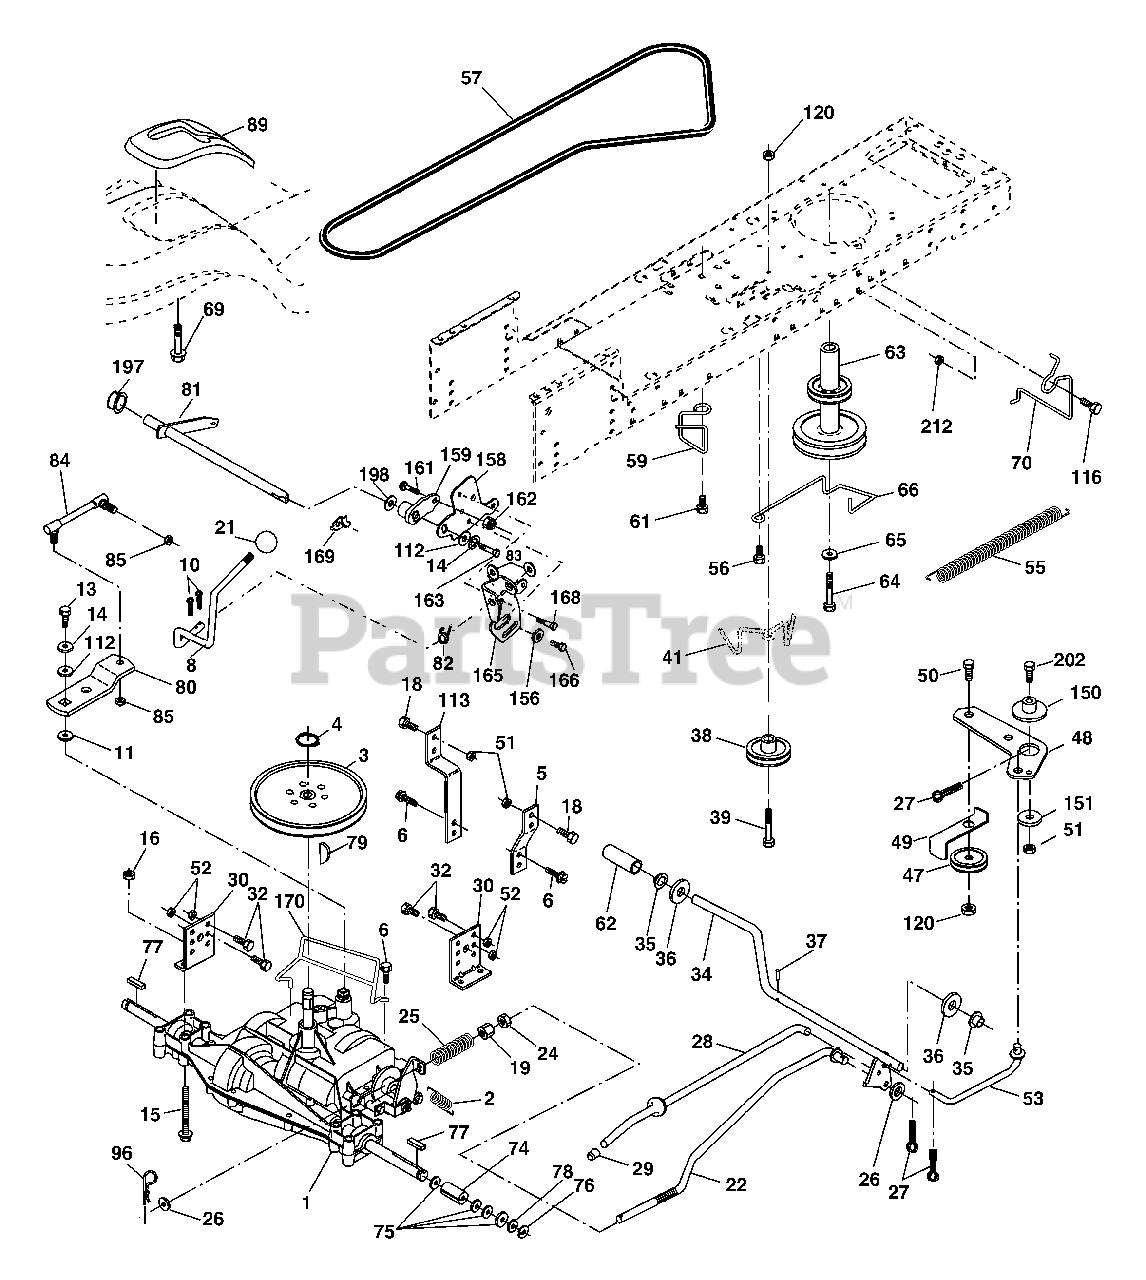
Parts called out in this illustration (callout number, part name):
2	Spring Return Brake T/a Zinc
3	Pulley Transaxle 18" tires
4	Ring Retainer # 5100-62
5	Strap Torque 30 Degrees
6	Screw 5/16-18 x 3/4
8	Rod Shift Fender Adjust Lt
10	Pin Cotter 1/8 x 1 Cad
11	Washer Plate Shf 388 Sq Hole
13	Bolt 1/4-28 unf Gr. 8 W/Patch
14	Washer Lock Hvy Helical
15	Bolt Hex FLGHD 5/16-18 Gr. 5
16	Nut Lock Hex w/ins 5/16-18
18	Bolt, Fin Hex 3/8-16 unc x 1 Gr. 5
19	Nut Lock 3/8-16 unc
21	Knob
22	Rod Brake Blk Zinc 26 840
24	Nut Hex Jam 3/8-16 unc
25	Spring Rod Brake 2 00 Zinc
26	Washer 13/32 x 13/16 x 16 Ga.
27	Pin Cotter 1/8 x 3/4 Cad
28	Rod Brake Parking LT/YT
29	Cap Brake Parking
30	Bracket Mtg Transaxle
32	Bolt Hex Hd 5/16-18 unc x 3/4
34	Shaft Asm Pedal Foot
35	Bearing Nylon Blk 629 Id
36	Washer 21/32 x 1 x 16 Ga
37	Pin Roll 3/16 x 1"
38	Pulley Composite Flat
39	Bolt Fin Hex 3/8-16 unc x 2-3/4
41	Keeper Belt Flat Idler
47	Pulley Idler V Groove Plastic
48	Bellcrank Asm
49	Retainer Belt Style Spring
50	Bolt Carr. Sh. 3/8-16 x 1-1/2 Gr. 5
51	Nut Crownlock 3/8-16 unc
52	Nut Crownlock 5/16-18 unc
53	Link Clutch
55	Spring Return Clutch 6 75
56	Screw 3/8-16 x 1-1/4
57	V-Belt Ground Drive 95 25
59	Keeper Belt Span Ctr
61	Screw 3/8-16 x .875
62	Cover Pedal Blk Round
63	Engine Pulley
64	Bolt Hex 7/16-20 x 4 x Gr. 5-1.5 Thr
65	Washer Lock Hvy Hlcl Spr 7/16
66	Keeper Belt Engine Foolproof
69	Screw Hex wsh Hi Lo 1/4 x 1/2 unc
70	Guide Belt Mower Drive RH
74	Spacer Axle
75	Washer 25/32 x 1 1/4 x 16 Ga.
76	E-ring #5133-75
77	Key Square 2 0 x 1845/ 1865
78	Washer 25/32 x 1-5/8 x 16 Ga.
79	Key Woodruff #9 3/16 x 3/4
80	Arm Shift
81	Shaft Asm Cross Tap. PMST/20
82	Spring Torsion T/a
83	Washer 17/32 x 3/4 x 16 Ga.
84	Link Transaxle PMST/18" Zinc
85	Nut Lock Center 1/4 - 28 FNTHD
89	Console Shift STLT
96	Retainer Spring 1"
112	Washer 9/32 x 3/4 x 10 Ga.
113	Strap Torque LT
116	Bolt Rdhd Sq Neck 3/8-16 x 1
120	Nut Lock Flg. 3/8-16 unc
150	Spacer Retainer
151	Washer 13/32 x 2 x 10
156	Washer Srrted 5/16 ID x 1.125
158	Bracket Shift Mount
159	Hub Tapered Flange Shift Lt
161	Bolt Rdhd Sqnk 1/4-20 x 3/4 Gr. 5
162	Nut Crownlock 1/4-20 unc
163	Bolt Hex Fin 1/4-20 unc x 1 Gr. 5
165	Bracket Pivot Lever
166	Screw 5/16-18 x 5/8
168	Bolt Shoulder 5/16-18 x .561
169	Plate Fastening
170	Keeper Belt Transaxle Gear
197	Nyliner Snap-In
198	Washer Nyliner
202	Bolt Rd Hd 3/8-16 unc x 1-3/4 Gr. 5
212	Nut Hexflange Lock
